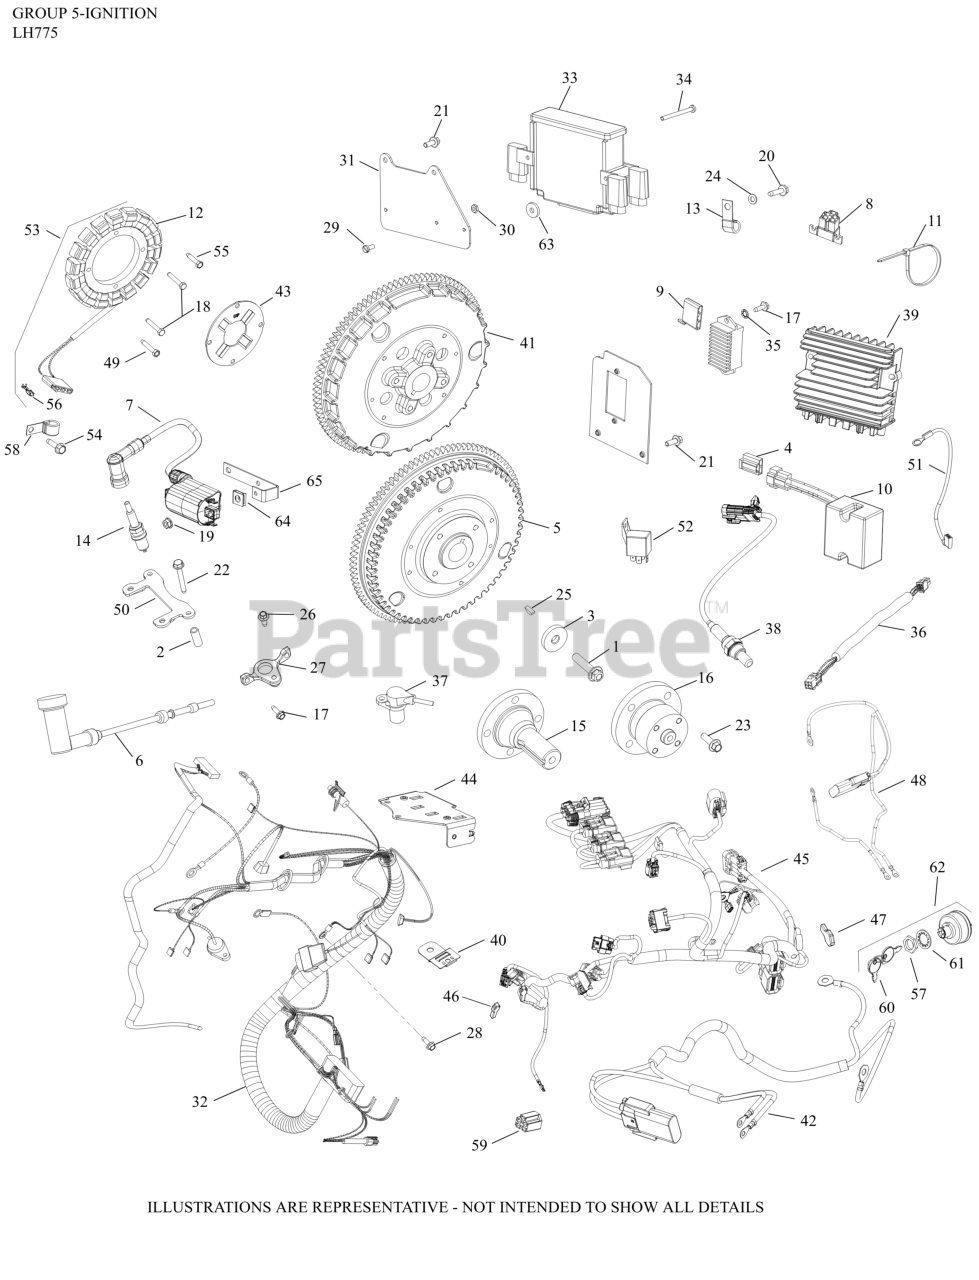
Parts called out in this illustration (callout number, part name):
1	SCREW, FLG M10X1.5X45-USE 25 086 361-S
3	WASHER, FLAT 13/32"
5	KIT, FLYWHEEL ASSEMBLY
6	BOOT, SPARK PLUG
7	COIL, IGNITION
14	SPARK PLUG
15	SHAFT, FRONT DRIVE
20	SCREW, THREAD FORMING
21	SCREW, FLG M6X1.0X16
22	SCREW, THRD FRM M6X1.0X45
23	SCREW, FLG M8X1.25X25
24	WASHER, FLAT 1/4" (O.D. 1/2")
25	KEY, 3/16" X 5/8"
27	BRACKET, SPEED SENSOR
28	SCREW, THREAD FORMING
30	NUT, MACH SCREW #10-32 GRD 2
32	HARNESS ASSEMBLY
33	MODULE, ENGINE MANAGEMENT (ECU)
35	WASHER, INT TOOTH LOCK #10
37	KIT, SPEED PICK-UP SENSOR
38	SENSOR, OXYGEN
54	SCREW, THREAD FORMING
64	CLIP, BAFFLE MOUNTING
65	BRACKET, IGNITION COIL (EFI)
